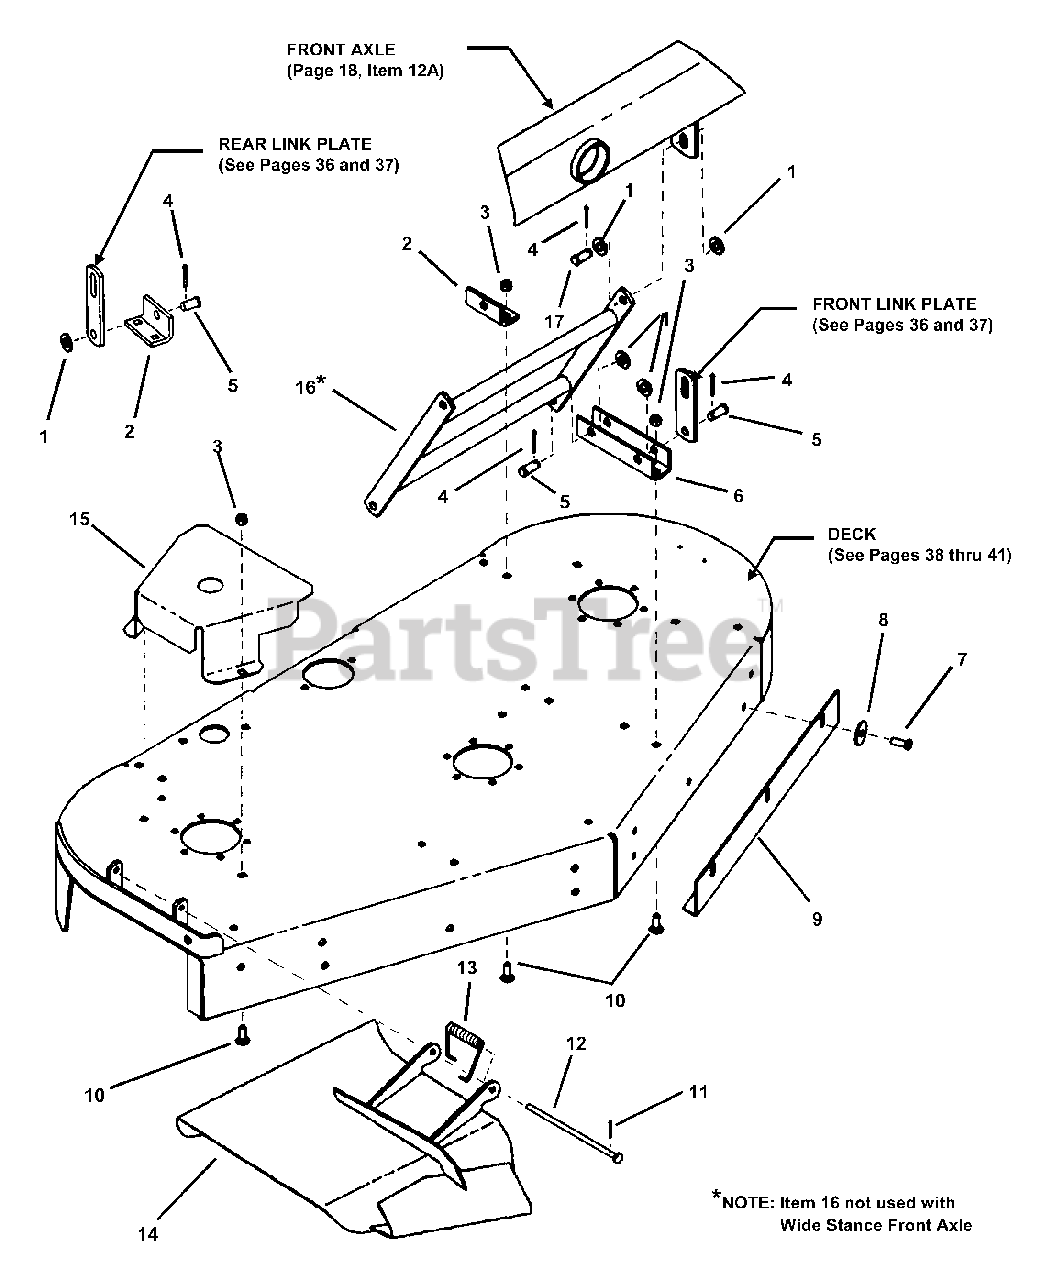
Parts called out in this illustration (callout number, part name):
1	WASHER, 17/32 x 1-1/16 Flat
2	BRACKET, Rear Lift
3	NUT, 3/8-16 HEX NYLON LOCK
4	PIN, 5/32 x 1" Cotter
5	PIN, 1/2 x 23/32 Clevis
6	BRACKET, Front Lift
7	BOLT, 3/8-16 X 1" GD5 CZ
8	WASHER, 13/32 x 1-1/2" Flat
9	BAFFLE, 52 Front
10	BOLT, 3/8-16 x 1" Carriage
11	PIN, 3/32 x 1" Cotter
12	PIN, Chute Hinge
13	SPRING, Chute
14	CHUTE, 52" Deck
15	COVER, Spindle
16	WELDMENT, Pull Bar
17	PIN, 1/2 x 1-1/8" Clevis
